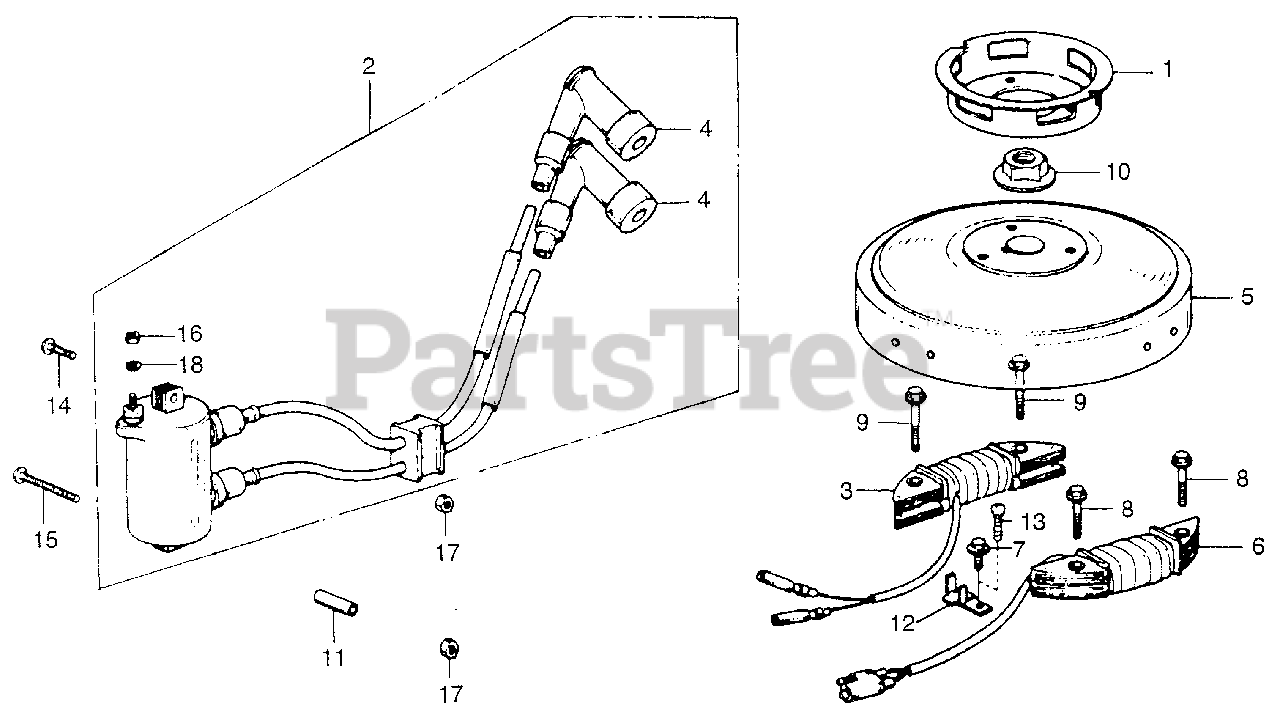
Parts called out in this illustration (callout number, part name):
1	PULLEY, STARTER
2	COIL ASSY., A.C. IGNITION (NOT AVAILABLE)
3	COIL ASSY., PRIMARY
4	CAP ASSY., NOISE SUPPRESSOR
5	FLYWHEEL *TBLACK* (BLACK)
6	COIL ASSY., CHARGE (NOT AVAILABLE)
7	BOLT, FLANGE (6X12)
8	BOLT, FLANGE (6X28)
9	BOLT, FLANGE (6X35)
10	NUT, SPECIAL (14MM)
11	COLLAR, DISTANCE
12	CLIP, WIRE
13	SCREW, PAN (6X12)
14	SCREW, PAN (6X25)
15	SCREW, PAN (6X50)
16	NUT, HEX. (5MM)
17	NUT, HEX. (6MM)
18	WASHER, SPRING (5MM)
